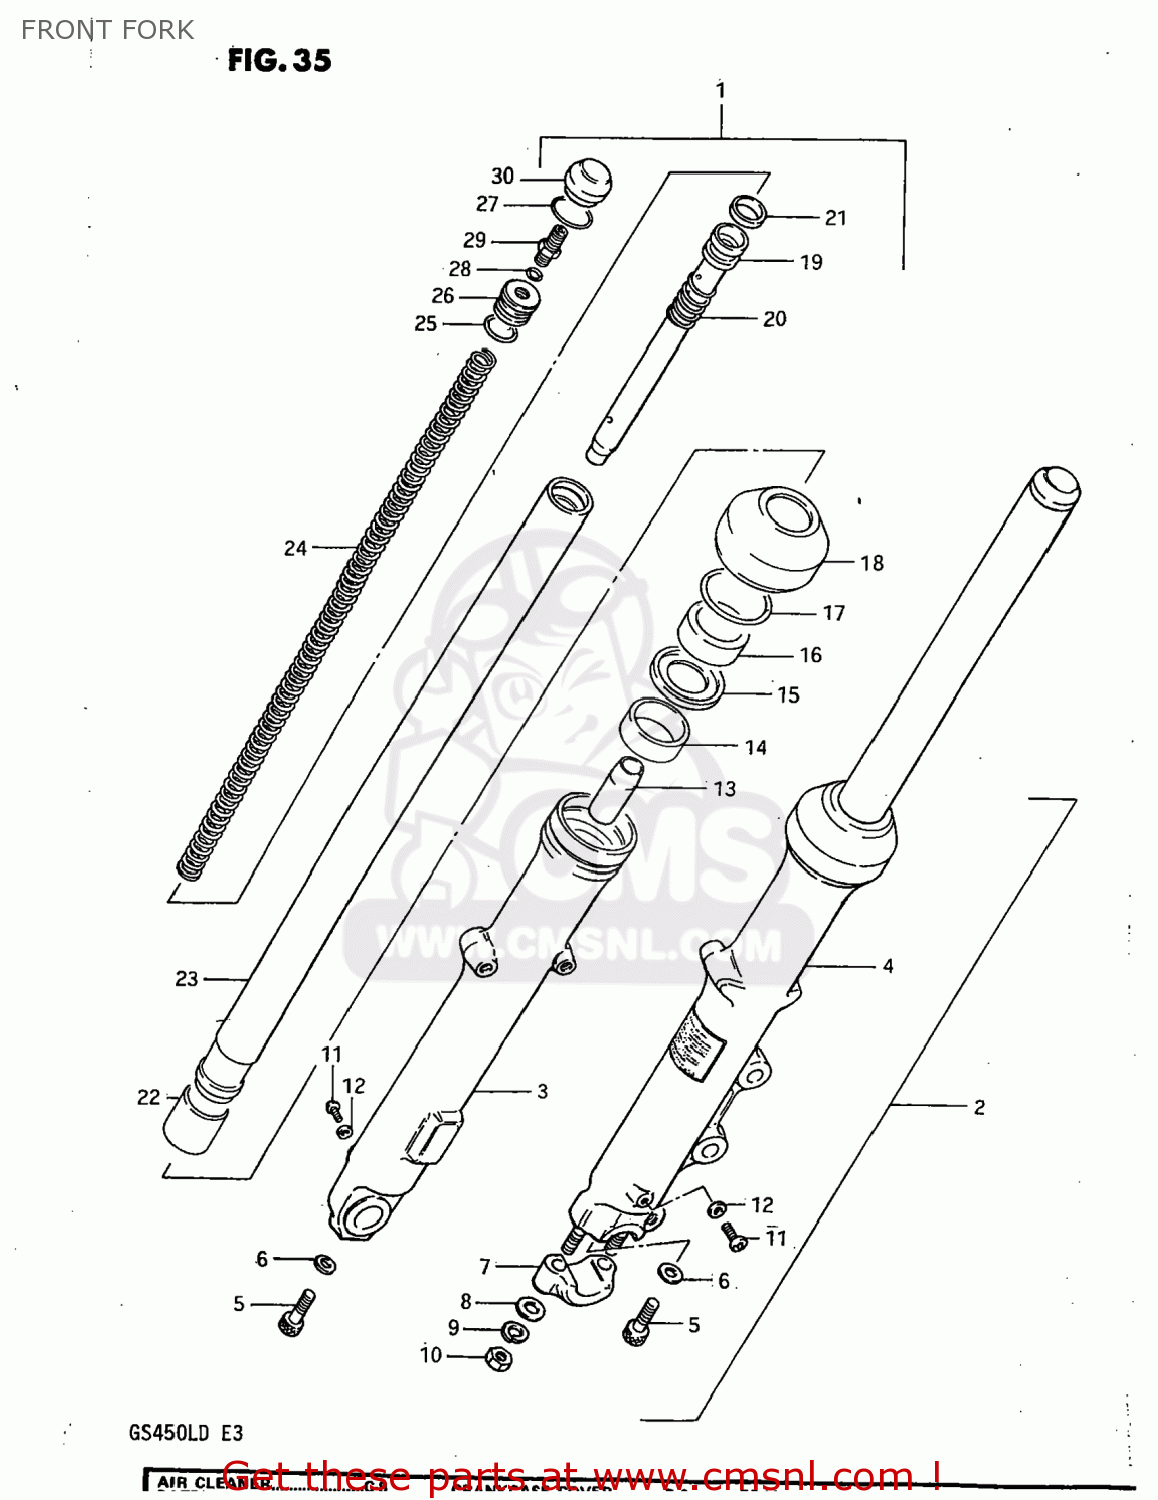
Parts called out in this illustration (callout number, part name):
1	DAMPER ASSEMBLY,FRONT FORK,RIGHT
2	DAMPER ASSEMBLY,FRONT FORK,LEFT
3	TUBE,FORK,OUTER,RIGHT
4	TUBE,FORK,LEFT,OUTER
5	BOLT(8X27)
6	GASKET (NAS)
7	HOLDER,AXLE
8	WASHER
9	LOCK WASHER
10	NUT (8MM)
11	BOLT
12	GASKET,DRAIN,PLUG (NAS)
13	PIECE,OIL LOCK
14	BUSH,GUIDE
15	SPACER,SEAL
16	OIL SEAL,FRONT FORK
17	CIRCLIP,FORK OIL SEAL
18	BOOT
19	CYLINDER,FRONT FORK
20	SPRING,FORK REBOUND
21	RING,PISTON
22	PISTON
23	TUBE,FRONT FORK,INNER
24	SPRING,FRONT FORK
25	O-RING
26	SEAT,SPRING
27	RING,STOPPER
28	O-RING
29	VALVE,AIR
30	CAP
